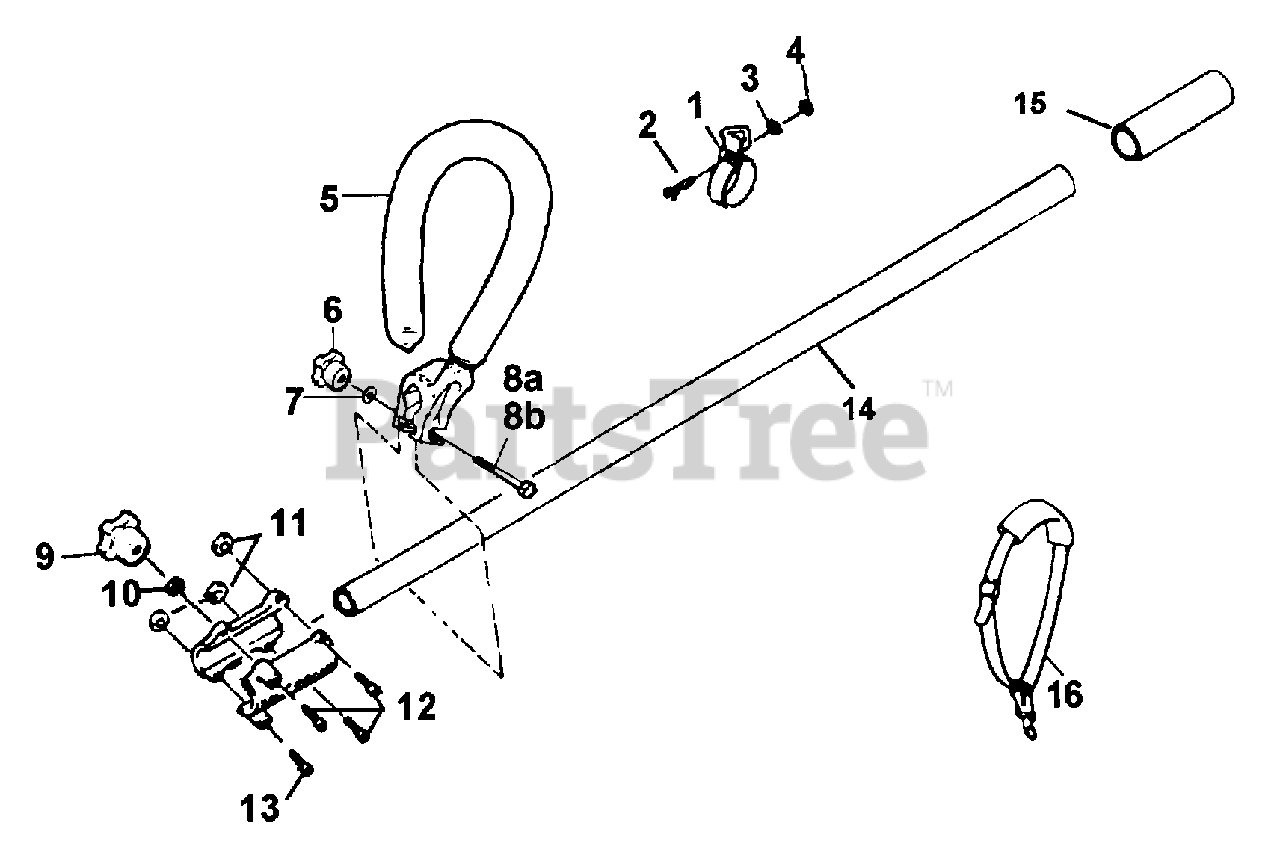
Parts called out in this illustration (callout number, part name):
1	HANGER ASSY.
4	NUT
5	HANDLE ASSY.
6	KNOB
8A	BOLT, HEX HEAD
8B	CARRIAGE BOLT
9	KNOB
11	NUT
12	BOLT
14	TUBE ASSY. W/DRIVESHAFT & LINER
16	HARNESS
